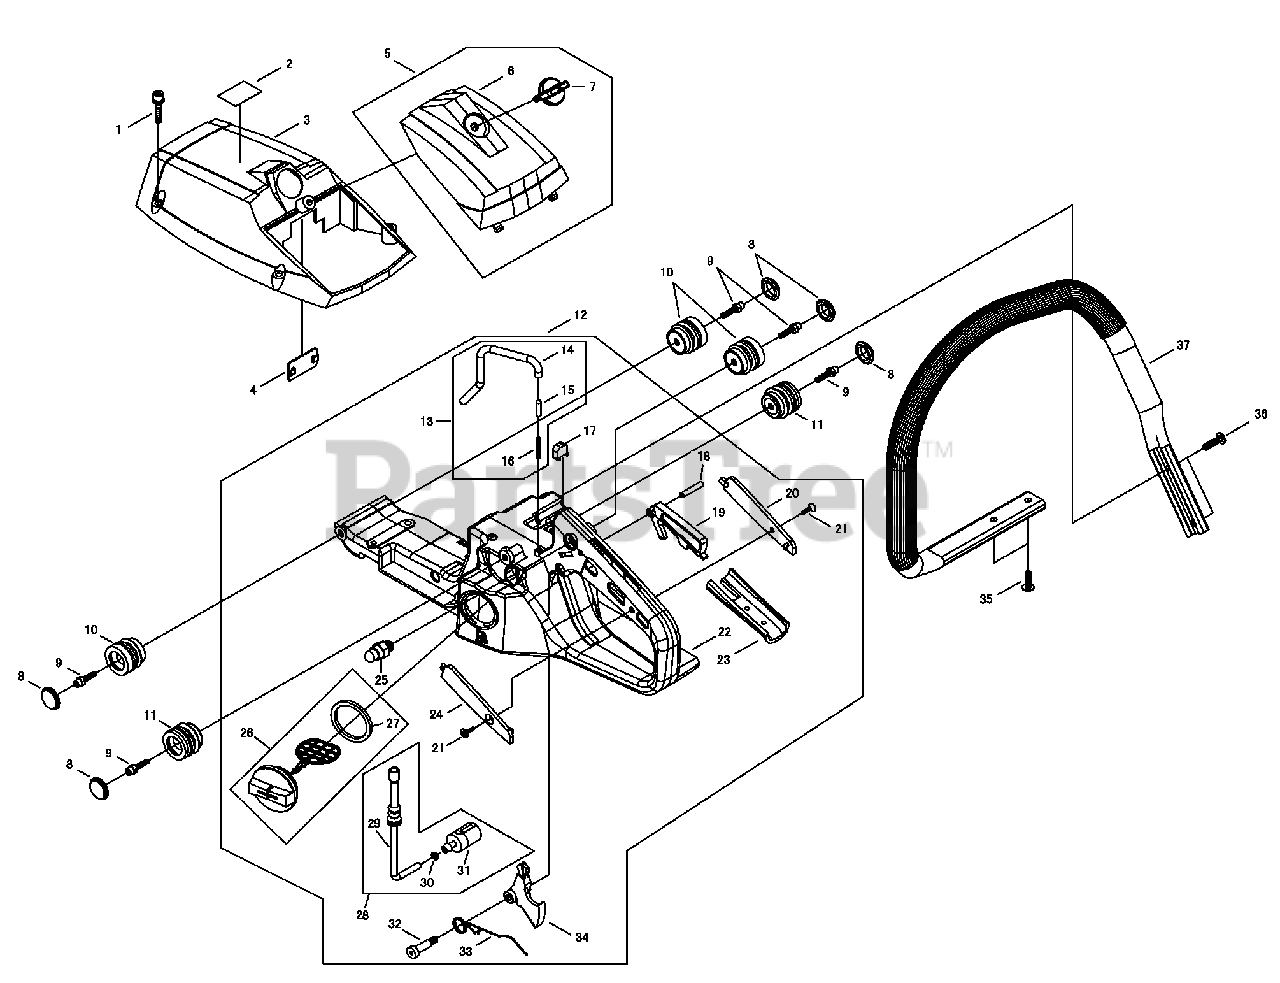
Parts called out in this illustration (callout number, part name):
1	BOLT 5
2	LABEL, CAUTION
3	COVER, ENGINE
4	PLUG
5	COVER, AIR FILTER
6	COVER, AIR FILTER
7	THUMBSCREW
8	PLUG
9	BOLT 5
10	CUSHION
11	CUSHION
12	HANDLE ASSY, REAR
13	BREATHER
14	PIPE, VENT
15	ELEMENT
16	SPRING
17	STOPPER
18	PIN, SPRING Ø4×25 MM
19	LEVER, LOCK
20	PLATE R
21	SCREW
22	HANDLE, REAR
23	GRIP
24	PLATE L
25	LOCKOUT, THROTTLE
26	CAP ASSY, FUEL
27	GASKET, FUEL CAP
28	PIPE ASSY, FUEL
29	PIPE, FUEL
30	CLIP Ø6
31	FILTER, FUEL
32	BOLT
33	SPRING, RETURN
34	LEVER, THROTTLE
35	BOLT, TAPPING M5×16
36	BOLT M5×20
37	HANDLE, FRONT
